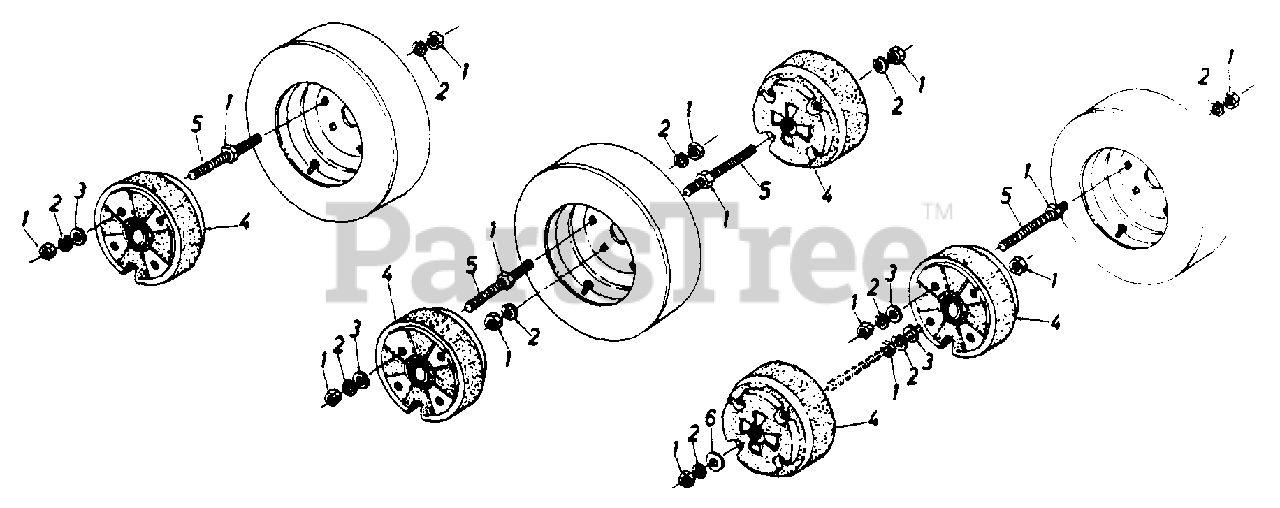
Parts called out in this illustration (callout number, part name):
1	Hex Nut 1/2-13 Thd.
2	Lock Washer 1/2" I.D.
3	Flat Washer .53" I.D. x .93" O.D.
4	Wheel Weight
5	Rod Threaded 1/2-13 x 9.50 Lg.
6	Fl.-Washer .50" 1.0. x 2.00" O.D.
